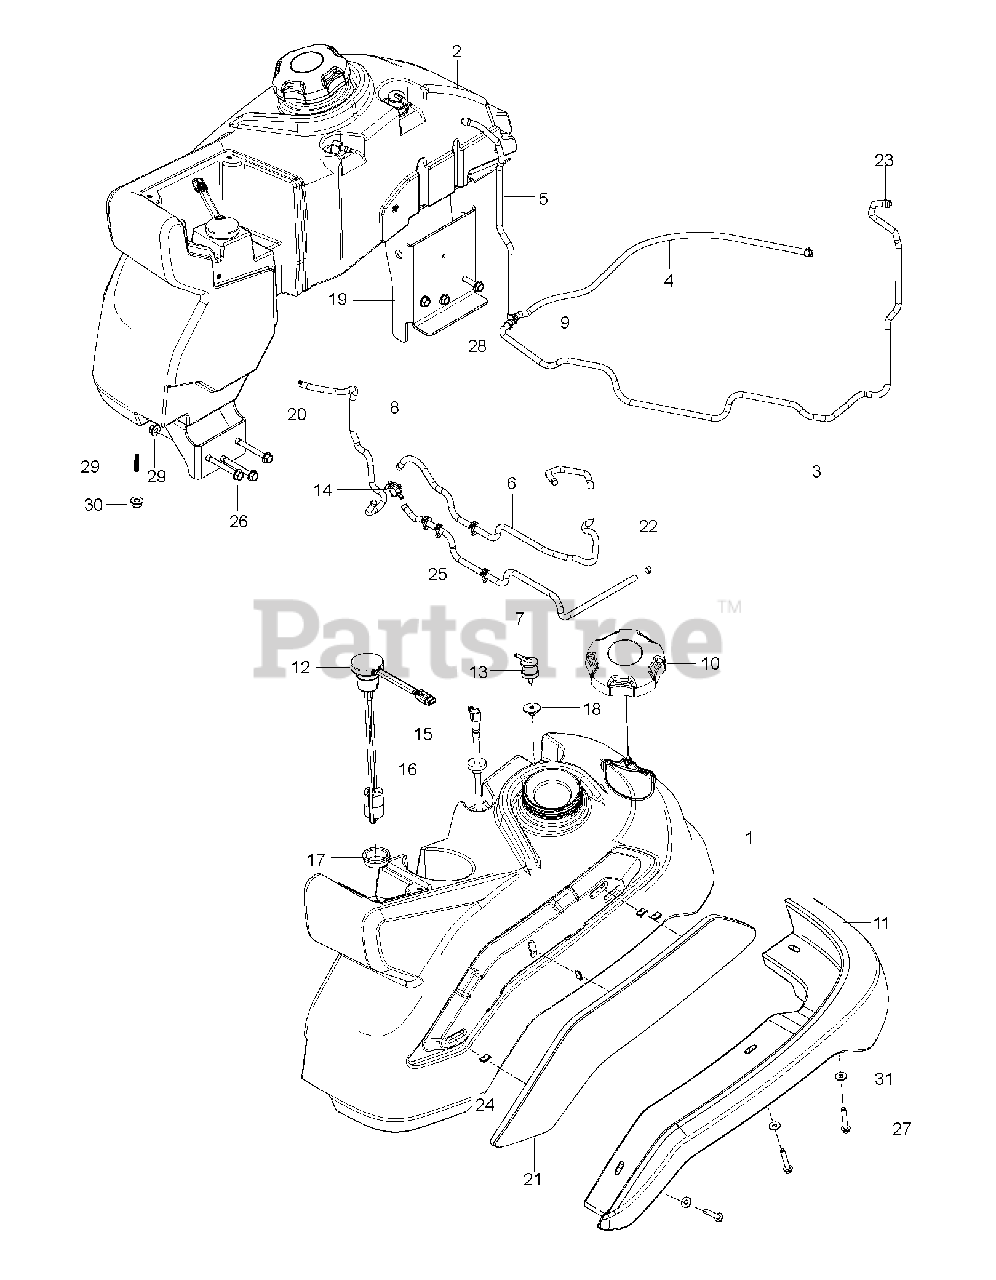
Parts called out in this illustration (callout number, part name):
1	FUEL.TANK.ASM.LH.PZ.REFRESH.18
2	FUEL.TANK.ASM.RH.PZ.REFRESH.18
3	HOSE.3/16".VAPOR.LINE.50"LGTH
4	HOSE.3/16".VAPOR.LINE.26"LGTH
5	HOSE.3/16".VAPOR.LINE.17"LGTH
6	HOSE.1/4".LOW.PERM.FUEL.LN.46"
7	HOSE.1/4".LOW.PERM.FUEL.LN.33"
8	HOSE.1/4".LOW.PERM.FUEL.LN.24"
9	TEE, FUEL LINE 3/16"
10	CAP, FUEL
11	GUARD.MUD.LH
12	SENSOR.FUEL.LVL.FLOAT.V500
13	VALVE.FUEL.CHECK
14	FUEL VALVE
15	TUBE.ASM.FUEL.TANK.PICK-UP.LH
16	BUSHING OUTLET T
17	GROMMET, FUEL SENSOR
18	Check Fuel Grommet
19	BRACKET.FUEL.TANK.REAR.SUP.431
20	BRACKET.FUEL.TANK.REAR.SUP.431
21	Fuel Tank Cover, LH Console App
22	HOSE CLAMP
23	CLAMP, HOSE
24	Clip, U Type
25	TIE WRAP, 8-3/8", W/CLIP
26	BOLT HEX FLGHD 5/16-18X3 GR. 5
27	SCREW.1/4-20X1.5IN.HEX.MACH
28	SCREW
29	SCREW.5/16-18X1.25"THREADED
30	5/16-18 NYLOC FLANGE NUT
31	WASHER
